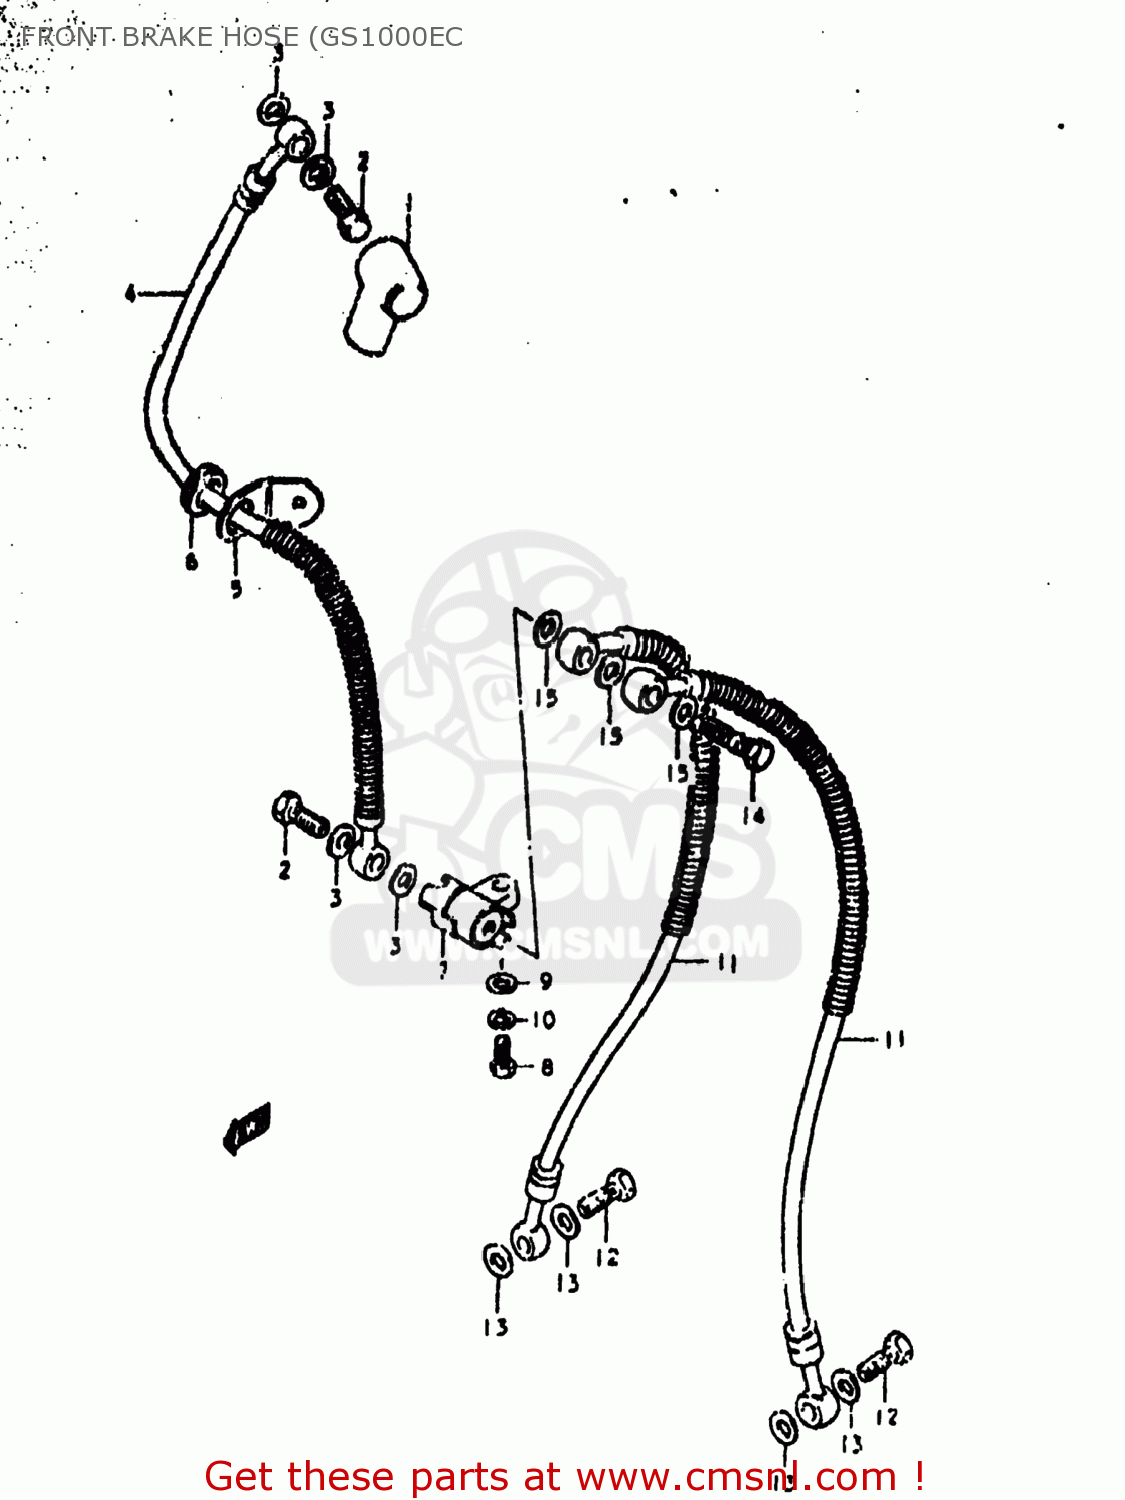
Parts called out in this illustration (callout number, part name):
1	BOOT,MASTER CYLINDER
2	BOLT UNION
3	WASHER
4	HOSE,FRONT BRAKE
5	GUIDE,BRAKE HOSE
6	GROMMET
7	JOINT,BRAKE HOSE
8	BOLT
9	WASHER
10	LOCK WASHER
11	HOSE,FRONT BRAKE
12	BOLT UNION
13	WASHER
14	BOLT UNION
15	WASHER
